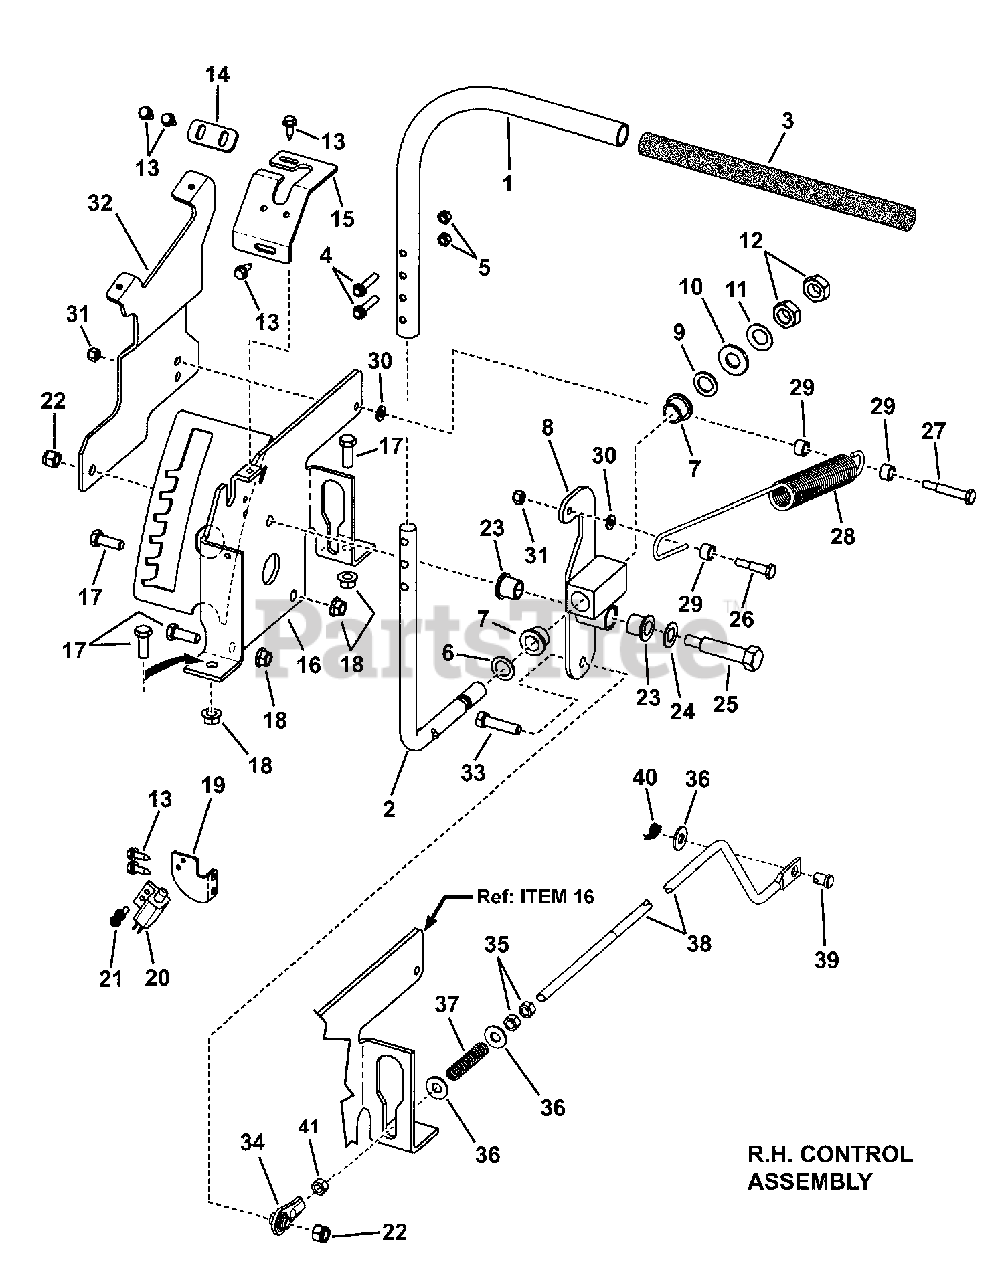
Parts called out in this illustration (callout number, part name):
1	HANDLE
2	R. H. CONTROL ARM (5/8" dia. Rod)
3	FOAM GRIP, Handle
4	SCREW, 1/4-20 x 1-1/4" Hex Head Cap, GR 5
5	NUT 1/4-20 Hex Center Lock, GR 5 YZ
6	WASHER, .64 x .99 x .05 Flat, YZ
7	BUSHING
8	WELDMENT, Control Arm, RH
9	WASHER, 5/8 ID x 1.00 OD x .065 Nylon
10	WASHER, 5/8 SAE Flat
11	WASHER, .64 x 1.12 x .028 Beveled
12	NUT, 5/8-18 Hex Jam
13	SCREW, 1/4-20 x 3/4" Hex Washer Self-Tap
14	PLATE, Fwd/Rev Adjust
15	TRACK, Control Stick, R.H.
16	WELDMENT, Lift Bracket
17	SCREW, 3/8-16 x 1" Hex Head Cap, GR 5, YZ
18	NUT, 3/8-16 Hex Flange Lock
19	BRACKET, Switch
20	SWITCH- DPDT
21	SCREW, #10-24 x 1/2" Hex Washer Self-Tap (Torx)
22	NUT, 3/8-16 Hex Nyloc
23	FLANGE BEARING, 9/16 I.D. P.M.
24	THRUST WASHER, .562 ID x 1.000 OD x .030/.032 Thick
25	SHOULDER BOLT, 3/8-16
26	SHOULDER BOLT, 5/16 x 1/4-20
27	SHOULDER BOLT, 5/16 x 1/4-20
28	SPRING, Extension, RTN, ERZT
29	SPACER, 9/16 OD x 12GA x .325
30	WASHER, 1/4" I.D. Flat
31	NUT, 1/4-20 Hex Nyloc
32	BRACKET, Fender Support, RH
33	SCREW, 3/8-16 x 1-1/2" Hex Head Cap, GR 5
34	ROD END
35	NUT, 3/8-24 Hex, GR B, YZ
36	WASHER, 7/16" Flat
37	SPRING, Compression (Brake)
38	ROD, Link Fwd./Rev. (3/8-24 thread)
39	CLEVIS PIN, 7/16 x 1"
40	COTTER PIN, 1/2 Self Locking, YZ
41	NUT, 3/8-24 Hex Jam
